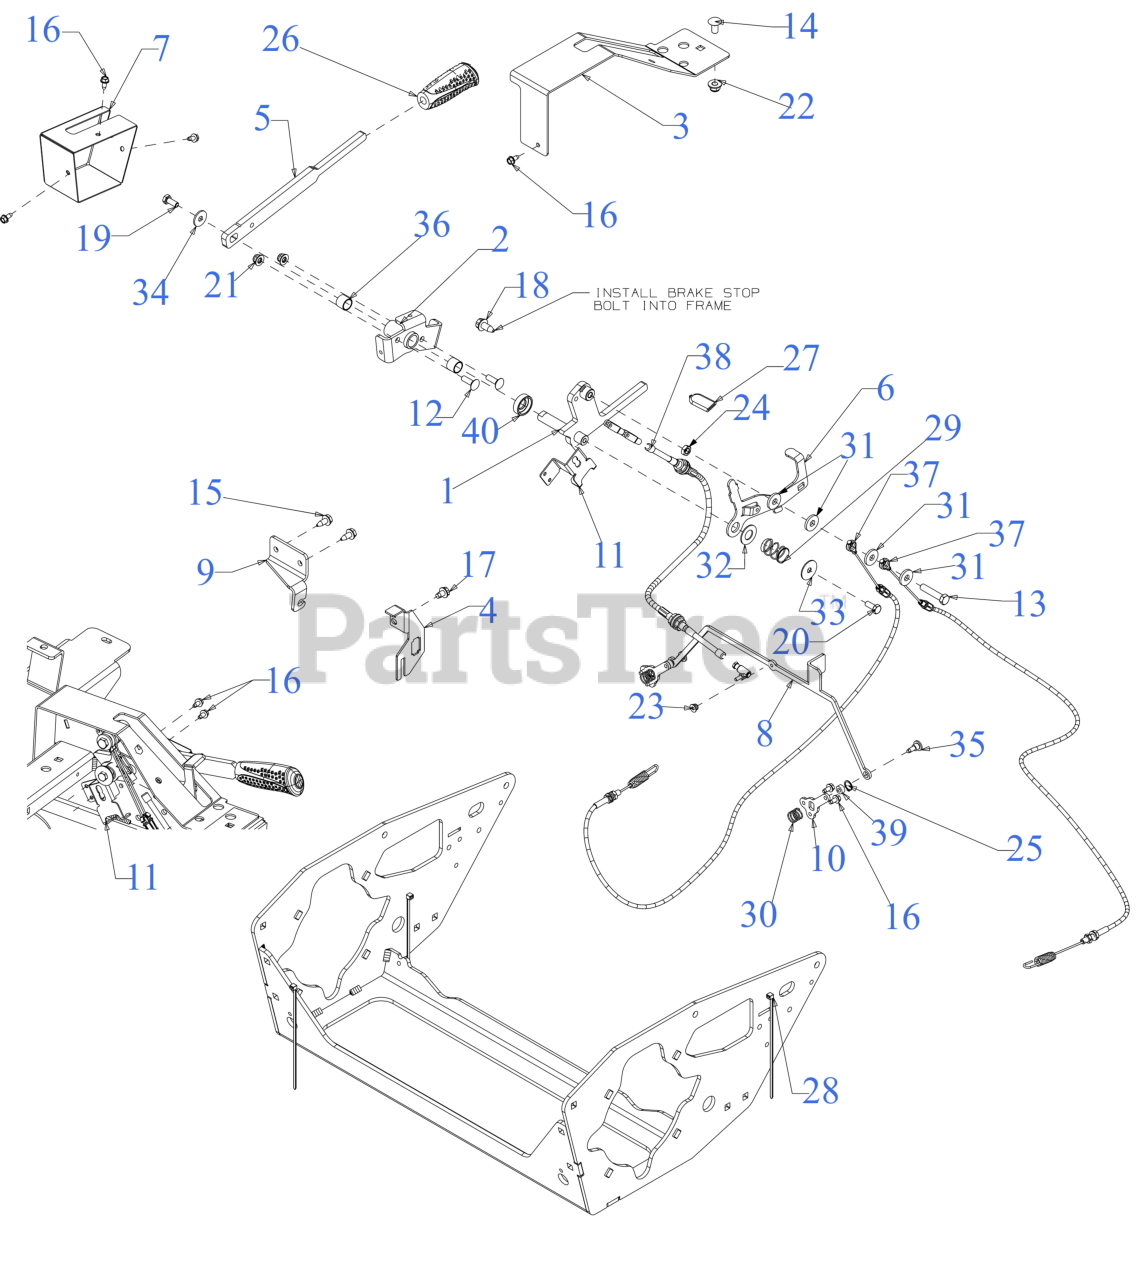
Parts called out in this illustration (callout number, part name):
1	BRAKE SHAFT PIVOT ASSEMBLY
2	PIVOT TUBE ASSEMBLY
4	NEUTRAL SWITCH MOUNTING BRACKET
6	DUMP VALVE RELEASE LEVER
8	DUMP VALVE ACTUATOR BRACKET
9	CABLE MOUNTING BRACKET
10	BYPASS LEVER
11	3-POLE SWITCH BRACKET
12	CARRIAGE BOLT 5/16-18 x 1.00
13	HEX SCREW 3/8-16 x 1.75 GR5
14	CARRIAGE BOLT 3/8-16 x .750 GR5
15	SCREW 5/16-18 x .750
16	SCREW 1/4-20 X.500
17	SCREW 5/16-18 x .500
18	HEX SCREW WASH TT 3/8-16 x .875
19	SCREW 5/16-18 x .750
20	SCREW 5/16-18 x .75 GR5
21	FLANGE LOCK NUT 5/16-18
24	HEX JAM NUT 3/8-16 GR5
25	SNAP RING FOR .562 DIA SHAFT
27	SEAT ADJUSTER GRIP
28	7" CABLE TIE
29	COMPRESSION SPRING .844X.970X1.50
30	COMPRESSION SPRING
31	FLAT WASHER .385 x 1.00 x .135
32	THRUST WASHER
33	FLAT WASHER .322 ID x 1.25 x .060
34	FLAT WASHER 1.0 OD:.331 ID
35	SHOULDER SCREW .375X.280:1/4-14
36	SLEEVE BEARING
37	BRAKE CABLE
38	NEUTRAL CONTROL CABLE
